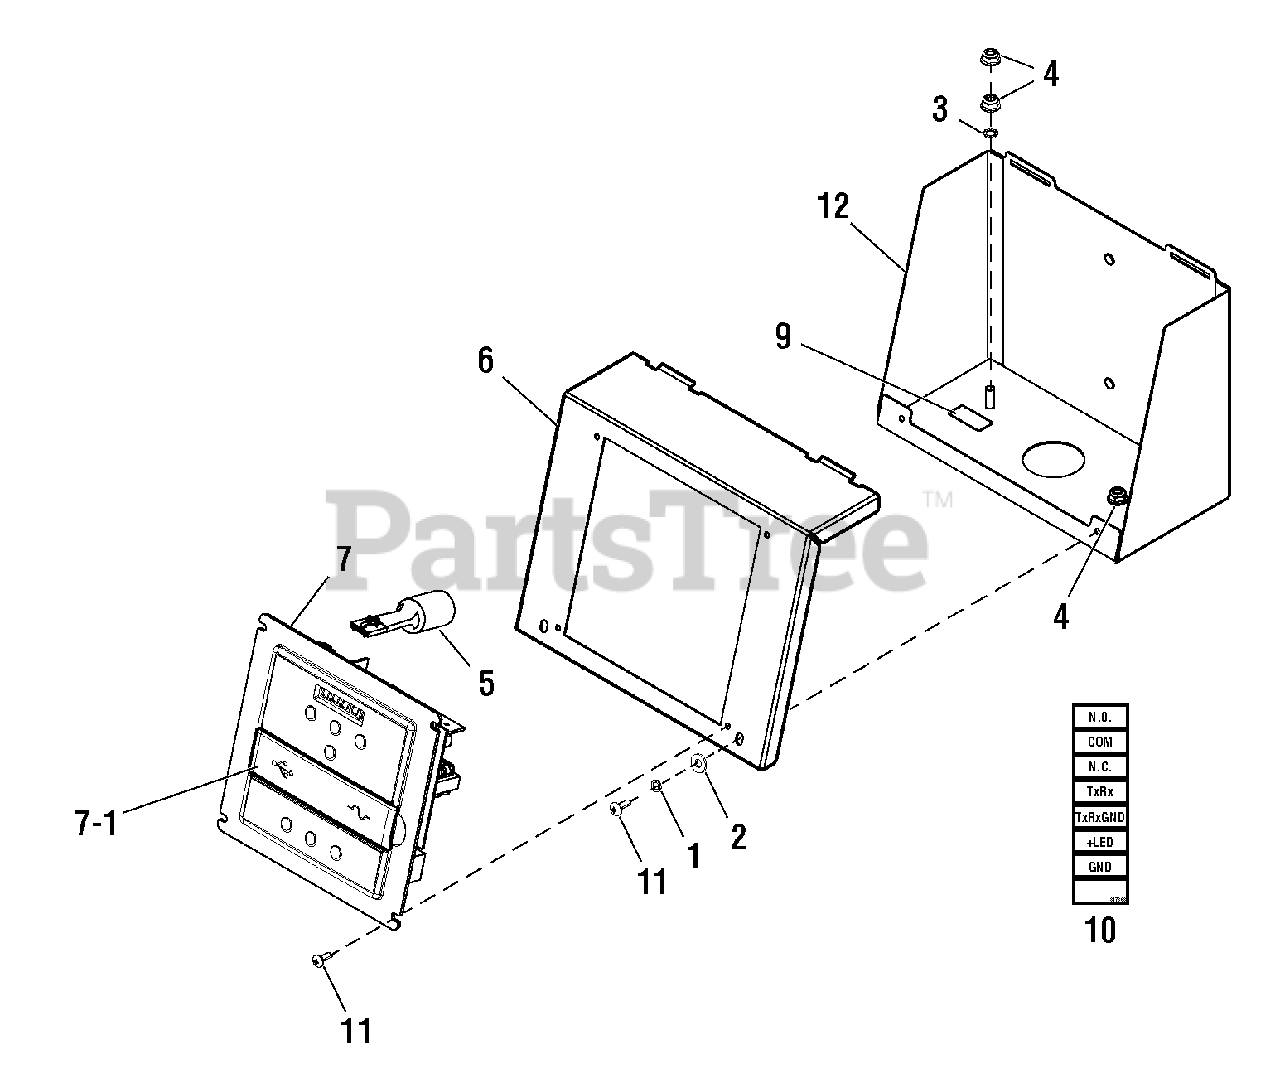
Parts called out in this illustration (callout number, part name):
1	* WASHER, Splitlock, #10
2	* WASHER, Flat, #10
3	* WASHER, Lock, Ext, M6
4	* NUT, Flange, Nylock, 1/4-20
6	COVER
7-1	DOOR
9	DECAL
11	* SCREW, Trilobular, 10-32 x 3/4
12	BOX-CONTROL PANEL
